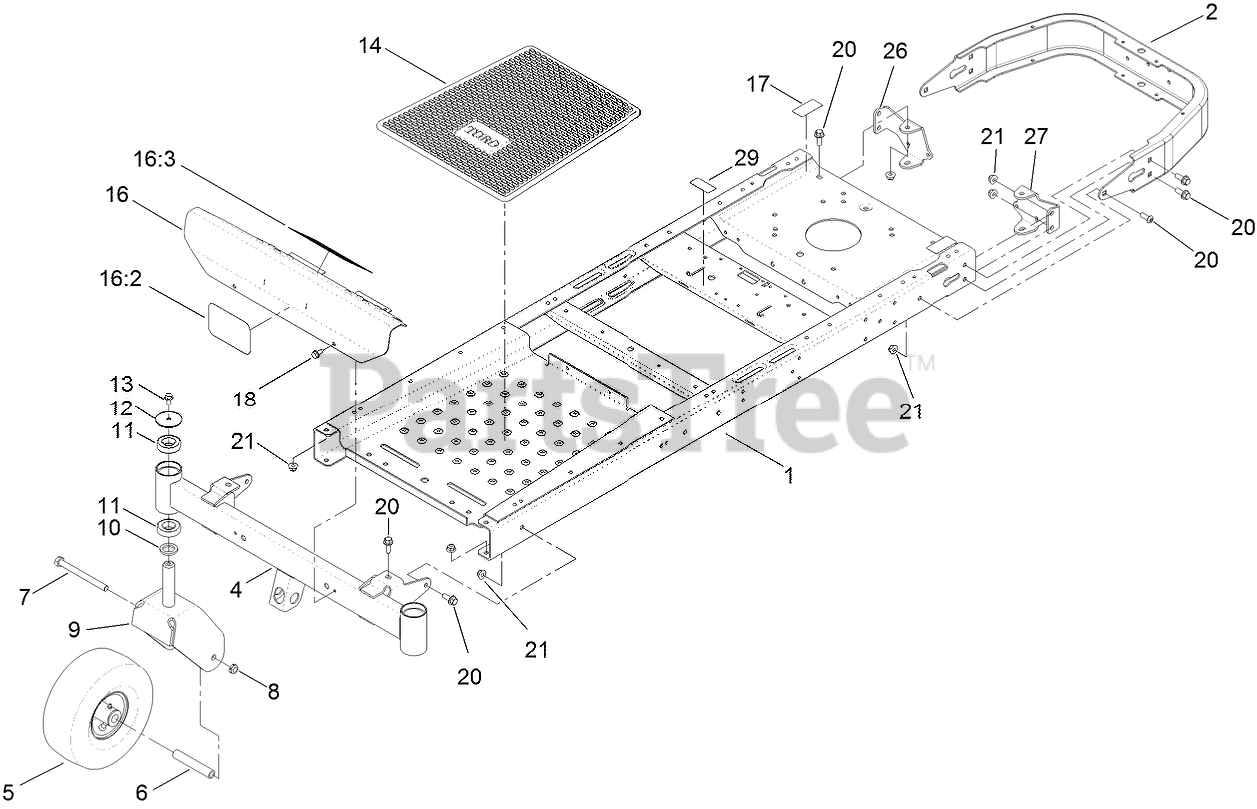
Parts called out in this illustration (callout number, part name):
2	BUMPER-REAR
4	AXLE-FRONT
5	CASTER WHEEL ASM (Cst)
6	BUSHING-SPANNER
7	SCREW-HH
8	NUT-LOCK, NI
9	FORK-CASTER
10	WASHER-THRUST
11	BEARING-BALL
12	WASHER
13	SCREW-HHF
14	MAT-FLOOR
16	FOOTREST ASM
16:3	DECAL-DANGER
17	DECAL-BYPASS
18	SCREW-HWHTF
20	SCREW-HHF
21	NUT-HF, NI
26	MOUNT-HYDRO, REAR (RH)
27	MOUNT-HYDRO, REAR (LH)
29	DECAL-LOCATION, SERVICE DEALER
